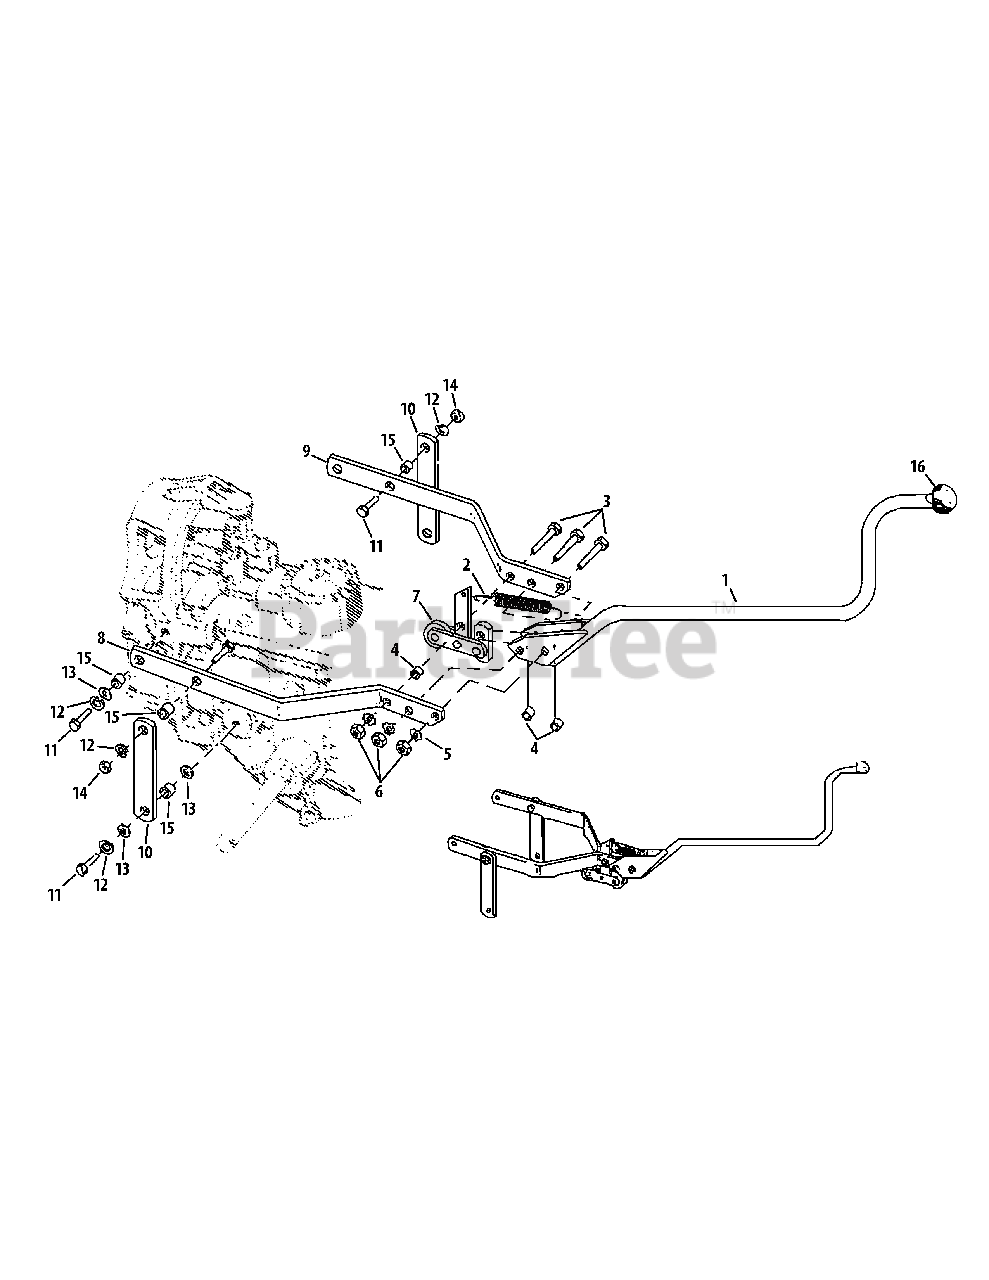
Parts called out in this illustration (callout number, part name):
1	Forward/Reverse Lever
2	Clutch Pawl Spring
3	Hex Bolt, 5/16-18 x 1-1/2
4	Bushing, .5 x .316 x .375
5	External Tooth Lockwasher, 5/16
6	Hex Nut, 5/16-18
8	Yoke (Left)
9	Yoke (Right)
10	Yoke Pivot Link
11	Hex Bolt, 3/8-16 x 1"
12	Lockwasher, 3/8
13	Flat Washer, 3/8
14	Hex Nut, 3/8-16
15	Bushing Spacer, .5 x .375 x .3
